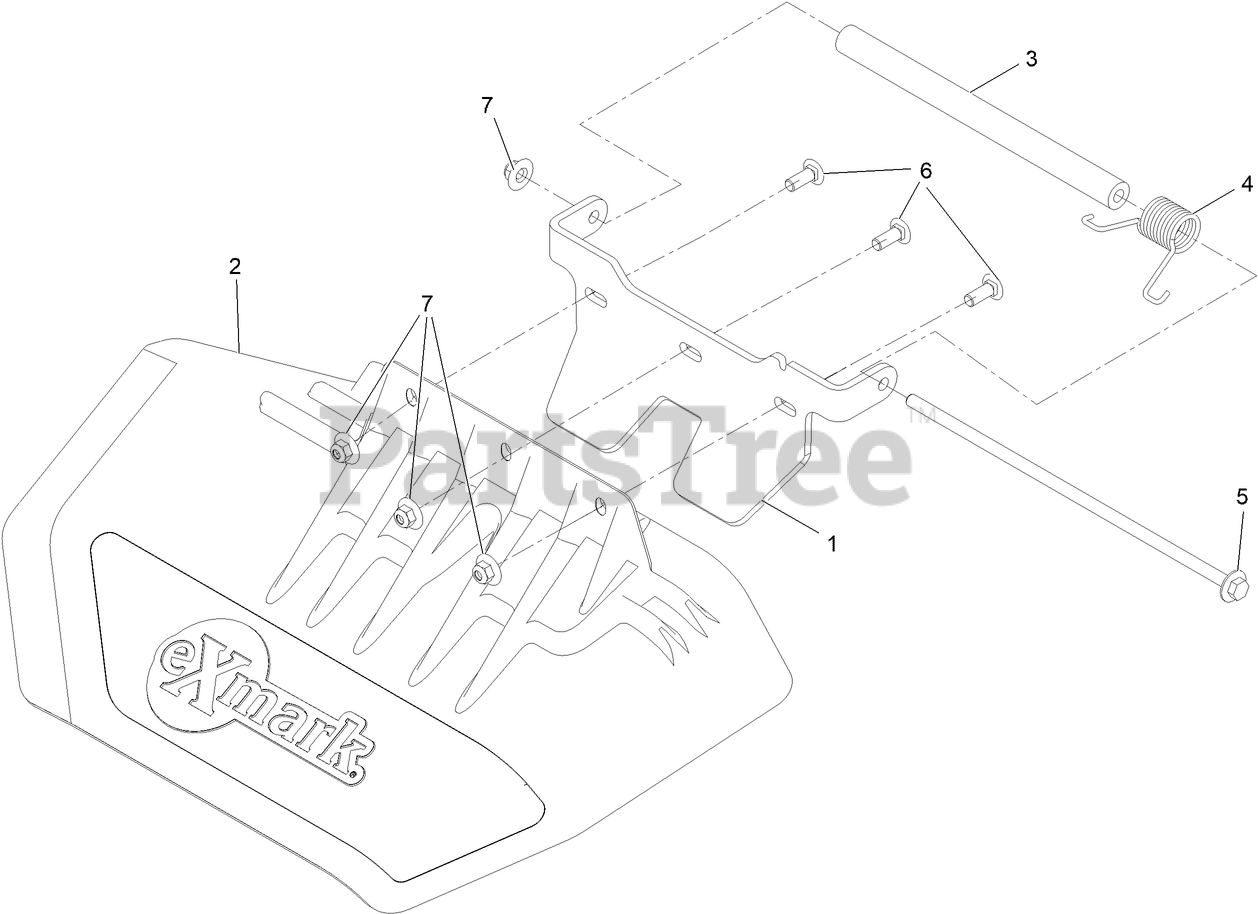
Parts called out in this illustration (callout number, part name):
1	Bracket, Discharge Chute
2	CHUTE- DISCHARGE
4	SPRING-TORSION
5	Pin, Chute
6	SCREW-CARR
7	Nut-Nyloc 3/8-16 Flg
